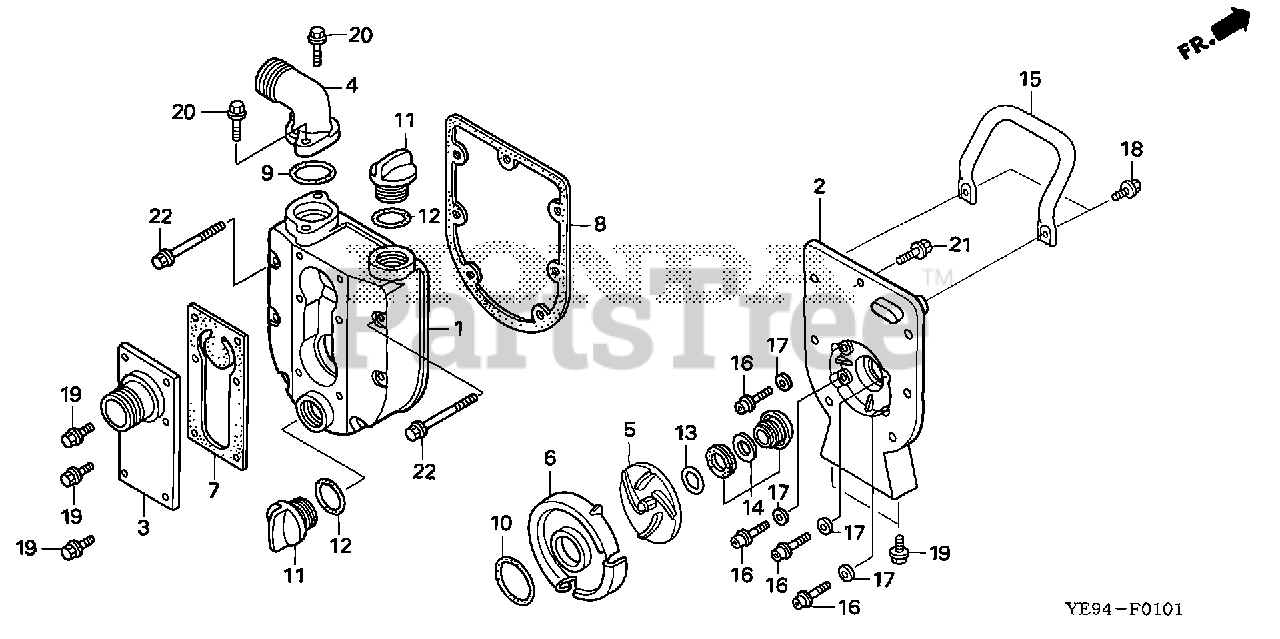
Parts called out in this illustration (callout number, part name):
1	CASING
2	PLATE, END
3	PLATE, SUCTION
4	PIPE, OUTLET
5	IMPELLER
6	CASE, VOLUTE
7	GASKET, SUCTION
8	GASKET, END PLATE
9	O-RING
10	RING A, SEAL
11	CAP, FILLER
12	RING, SEAL (B)
13	SHIM, ADJUSTER
14	SEAL ASSY., MECHANICAL
16	BOLT, FLANGE SOCKET (5X35)
17	WASHER, SEALING (5MM)
18	BOLT, FLANGE (6X12)
19	BOLT, FLANGE (6X14)
20	BOLT, FLANGE (6X18)
21	BOLT, FLANGE (6X18)
22	BOLT, FLANGE (6X55)
